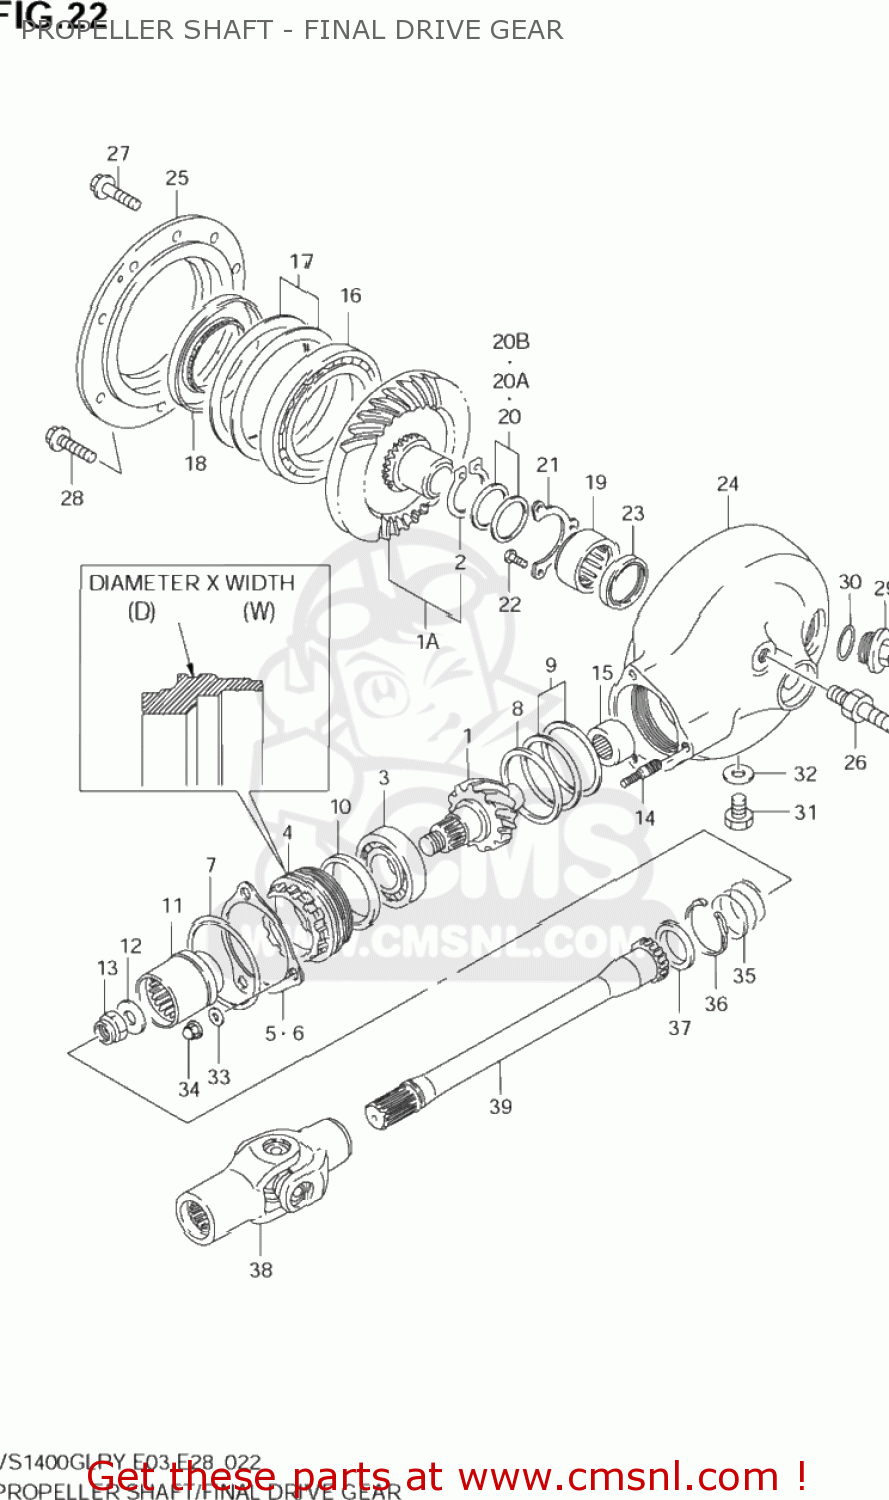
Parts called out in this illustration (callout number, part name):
1	GEAR,FINAL DRIVE BEVEL
1A	GEAR,FINAL DRIVEN BEVEL
2	.CIRCLIP
3	BEARING(28X68X18)
4	STOPPER,FINAL DRIVE BEARING
5	PLATE,BEARING STOPPER
6	PLATE,BEARING STOPPER
7	O RING(D:3.1,ID:63.9)
8	WASHER(54X68X1.5)
9	SHIM SET,FINAL DRIVE GEAR
10	SEAL,OIL
11	COUPLING,FINAL DRIVE GEAR
12	WASHER(16X29X4)
13	NUT
14	STUD 10X25
15	BEARING(20X34X18)
16	BEARING(85X130X14)
17	SHIM SET,FINAL DRIVEN GEAR
18	SEAL,OIL(70X110X14.7)
19	BEARING(35X48X23.7)
20	WASHER(35X46X0.95)
20A	SHIM SET,FINAL DRIVEN
20B	SHIM SET,FINAL DRIVEN GEAR
21	RETAINER,FINAL DRIVEN GEAR BRG
22	SCREW
23	SEAL,OIL(35X43X5)
24	CASE,FINAL GEAR
25	CASE,FINAL GEAR BEARING
26	BOLT,STUD
27	BOLT
28	BOLT
29	PLUG,30X9
30	O RING(D:3.1,ID:26.4)
31	PLUG
32	GASKET(13.8X18.8X4.8) (NAS)
33	WASHER
34	NUT
35	SPRING
36	CIRCLIP
37	SEAL,OIL(30X40.5X5.5)
38	YOKE COMP,UNIVERSAL JOINT
39	SHAFT,PROPELLER
